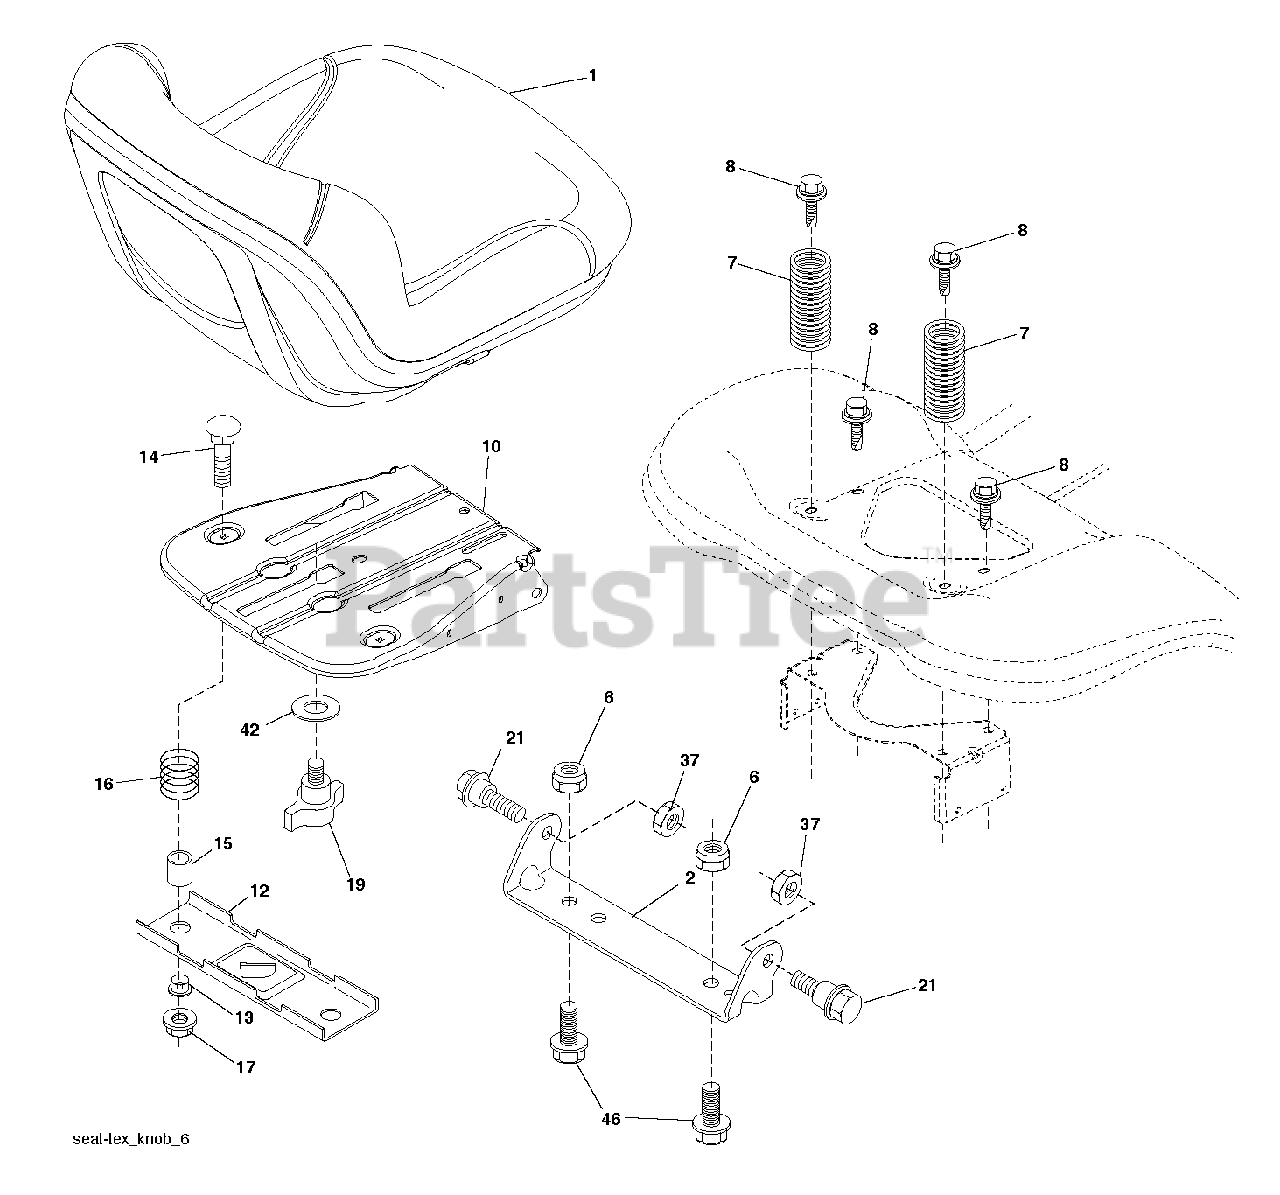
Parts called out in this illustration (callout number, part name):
2	BRKT.PIVOT.FENDER
6	NUT
7	Compression Spring, Seat Black
8	BOLT, 5/16-18 X 1 3/4
10	PAN.ASM.SEAT.SHORT.SLD.ADJ.TEX
12	BRKT.MNT.OPC.SW.SEAT.
14	BOLT.ROUND.HEAD.SQUARE.NECK
15	SPACER SPLIT 28X.96
16	SPRING COMPRESSED
17	NUT T
19	KNOB.SEAT.ADJ.
21	Shoulder Bolt, 5/16-18 X 5/8
37	NUT.71038.31-18.HEX.NYLOCK
42	WASHER.CUP.SEAT.
46	BOLT.3/8-16X1;1.25OD.WSHR.SEMS
